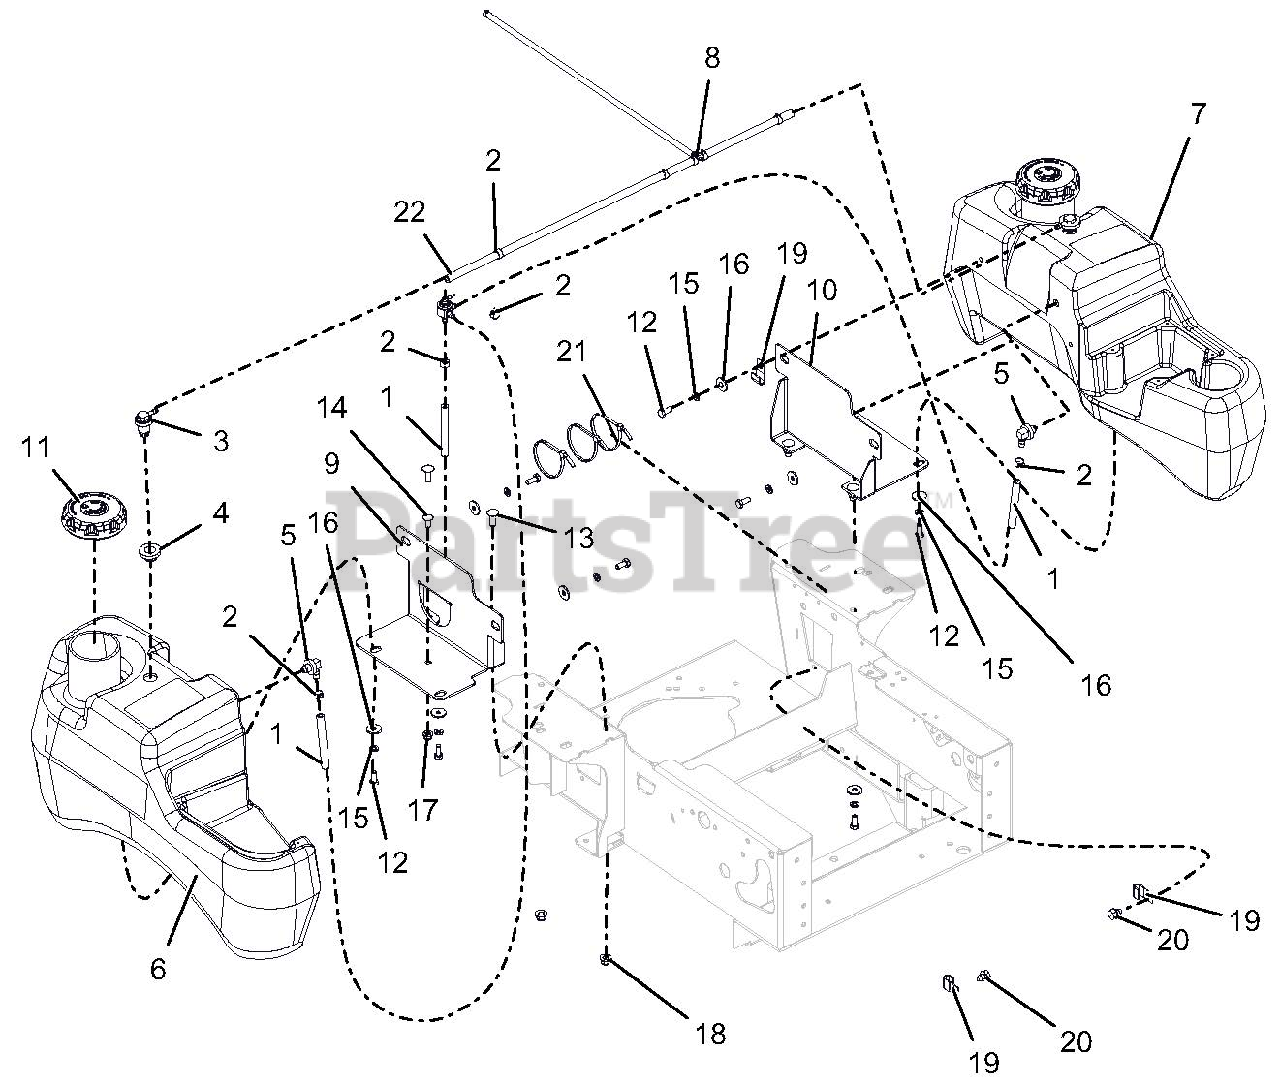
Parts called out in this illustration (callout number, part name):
1	.25 LOW-PERM GAS HOSE
2	CLAMP, FUEL LINE
3	VALVE, 2-WAY
4	GROMMET, REMOTE VENT NITRILE
5	ASS'Y, SMALL/ MED TANK FUEL PICK-UP
6	TANK, GAS - RH MEDIUM GRAVELY
7	TANK, GAS - LH MEDIUM GRAVELY
8	ASM, PT100 KAW FUEL LINE
9	BRKT, RH MEDIUM FUEL TANK MTG
10	BRKT, RH MEDIUM FUEL TANK MTG
11	CAP, FUEL VENT-IN AUTOLOCK
12	BLT-HEX .31-18X.75 GR5 YWZC
13	BLT-RDHDSHSQNK.38-16X1.0 G5YZ
14	BLT-RDHDSQNK .31-18X.75 G5 YWZC
15	WSHR-LK .31X.078 REG YWZC
16	WSHR-FL-STL .328X1.00X.094 YWZC
17	NUT-LK-NYL-FLG .31-18 YWZC
18	NUT-LK-NYL-FLG .38-16 YWZC
19	CLAMP, J
20	SCR-TAP .38-16X.50 HWH TR YWZ
21	CABLE, TIE 5.50 LG
22	VALVE, FUEL
